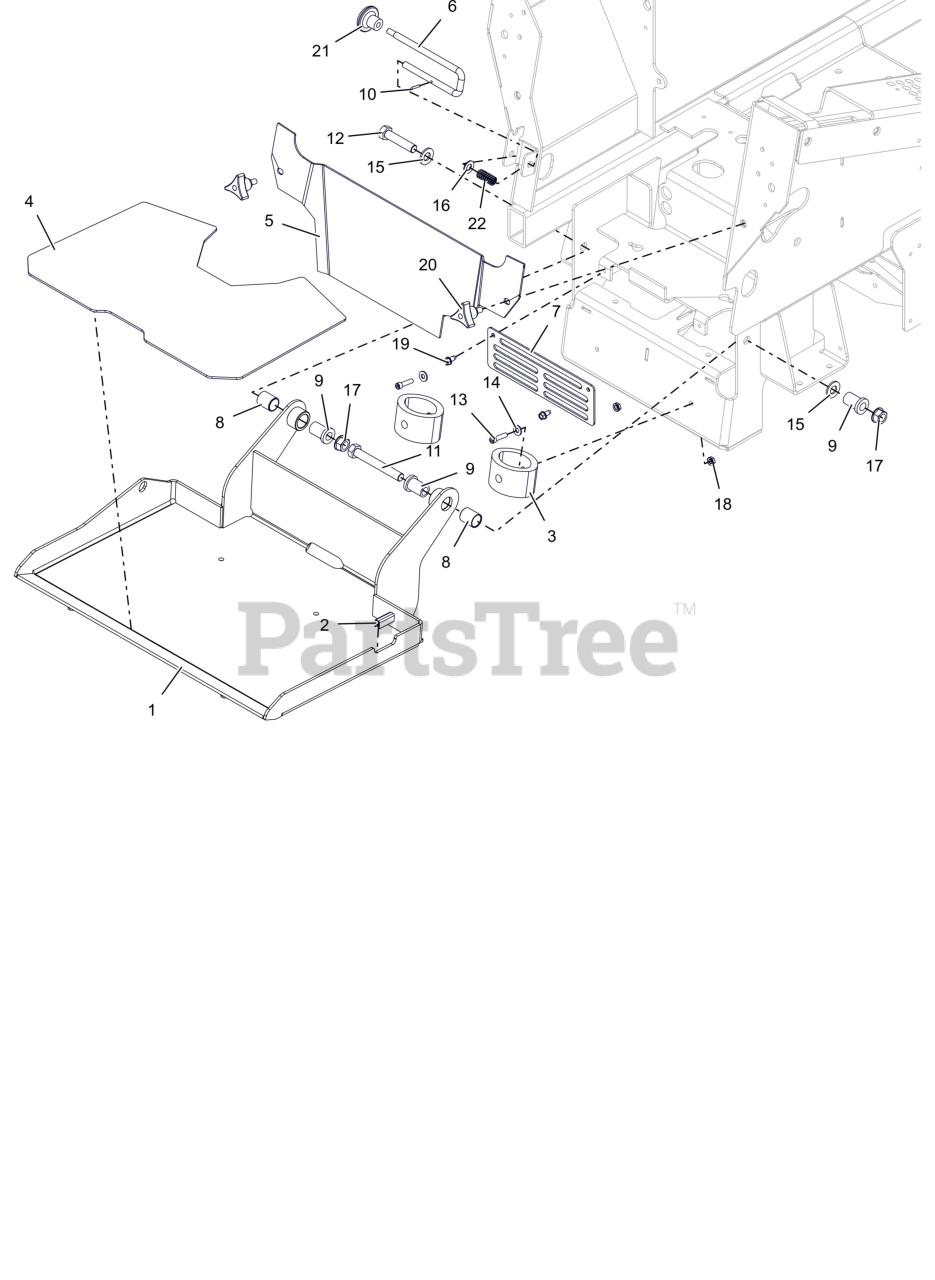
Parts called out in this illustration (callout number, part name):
1	PLATFORM, 32-36" OPERATOR (BLACK)
2	STRIP, COWL
3	BUMPER, PLATFORM
4	TAPE, OPERATOR PLATFORM GRIP
5	COVER, REAR TOWER (BLACK)
6	PIN, PLATFORM LOCK
7	GUARD, FOOT (ORANGE)
8	BRG, .750 X .875 X 1.000
9	BSHG-FLG .515X.746X1.290X1.000
10	PIN-ROLL .125X.75
11	BLT,HEX .50-13X3.75 G5 ZCC
12	BLT, HEX .50-13X2.25 G5 ZCC
13	SCR, SKH .25-20X1.00
14	WSHR,FLT .281X.625X.065 ZCC
15	WSHR,FLT .531X1.062X.095 ZCC
16	WSHR,FLT-HRD.406X.812X.055 MZC
17	NUT-LK-CTR-FLG .500-13 GG ZCC
18	NUT-KEPS .250-20 ZCC
19	SCR-TAP .25-20X.50 HWH ZCC
20	KNOB,WING STUD 5/16-18 X .75
21	KNOB, PUSH -PULL .312-18
22	SPRING, COMPRESSION
